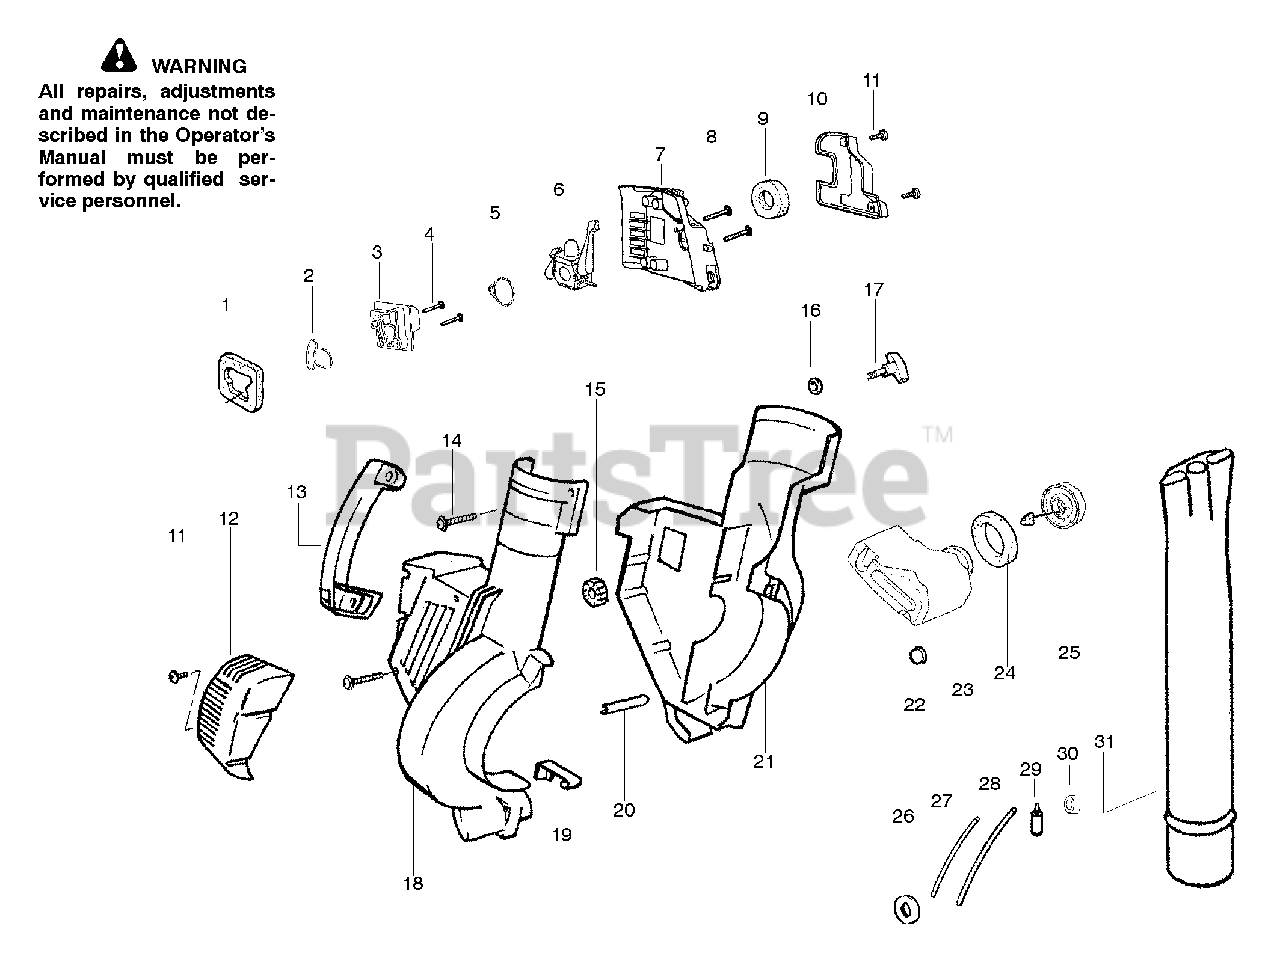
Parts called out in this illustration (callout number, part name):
1	Air Dam (kit)
2	Gasket-Adapter (kit)
3	Carburetor Adaptor
5	Gasket-Carburetor (kit)
6	Kit-Carb Ass'y (C1Q-W11)
6	Kit-Carb Ass'y (C1Q-W11C)
6	Kit-Carb Ass'y (WT-606)
8	Screw-Carb.
9	Filter-Air
10	Cover-Air Filter
12	Guard-Muffler
15	Isolator
17	Knob-Blower
18	Housing-Right
19	Spring-Cover Latch
20	Guide-Starter Rope
21	Housing-Left
22	Isolator-Crankcase
23	Assy-Fuel Tank
24	Gasket-Fuel Tank
25	Fuel Cap w/Retainer
26	Grommet-Shroud
27	Kit-Line Carb/Purge
28	Kit-Line Tank/Purge
29	Assy-Fuel Pick-up
30	Grommet-Fuel line (kit)
31	Tube - Blower BV - 1850
31	Tube - Blower BV - 2000
